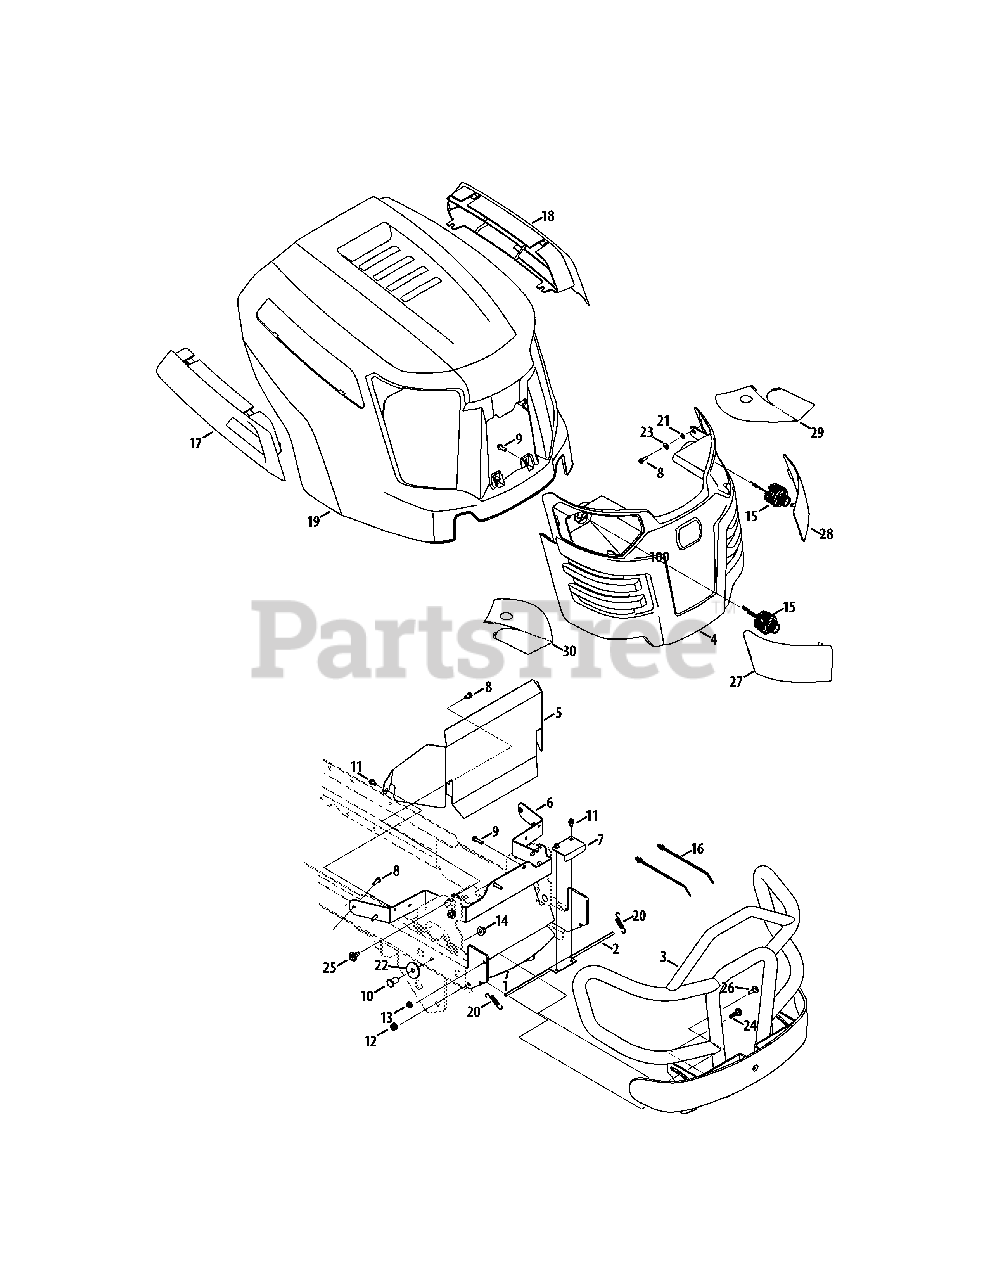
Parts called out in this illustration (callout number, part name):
1	Brush Guard Assembly
3	Brush Guard Tilt Bumper Assembly
4	Grill
5	Heat Shield
6	Hood Pivot Bracket
7	Brush Guard Tilt Lever Bracket
8	Hex Washer Screw, 1/4 x .750
9	Hex Washer Screw, 5/16-14 x 1.00
10	Hex Screw, 3/8-16 x 1.00
11	Hex Washer Screw, 1/4-20 x 0.500
12	Flange Lock Nut, 5/16-18
13	Flange Lock Nut, 1/4-20
14	Flange Lock Nut, 3/8-16
15	LED Headlight Socket
16	Cable Tie, 7.5
17	RH Hood Scoop
18	LH Hood Scoop
19	GT LE Hood
20	Extension Spring, .38 x 3.6
21	Lock Washer, 1/4
22	Flat Washer, .390 x 1.500 x .134
23	Flat Washer, .271 x .630 x .065
24	Shoulder Screw, 5/16-18 x .437 x .268
25	Shoulder Screw, 5/16-18 x .43 x .29
26	Shoulder Screw, 1/4-20 x .375 x .280
27	RH Hood Lens
28	LH Hood Lens
29	Left Lens Reflector Label
30	Right Lens Reflector Label
